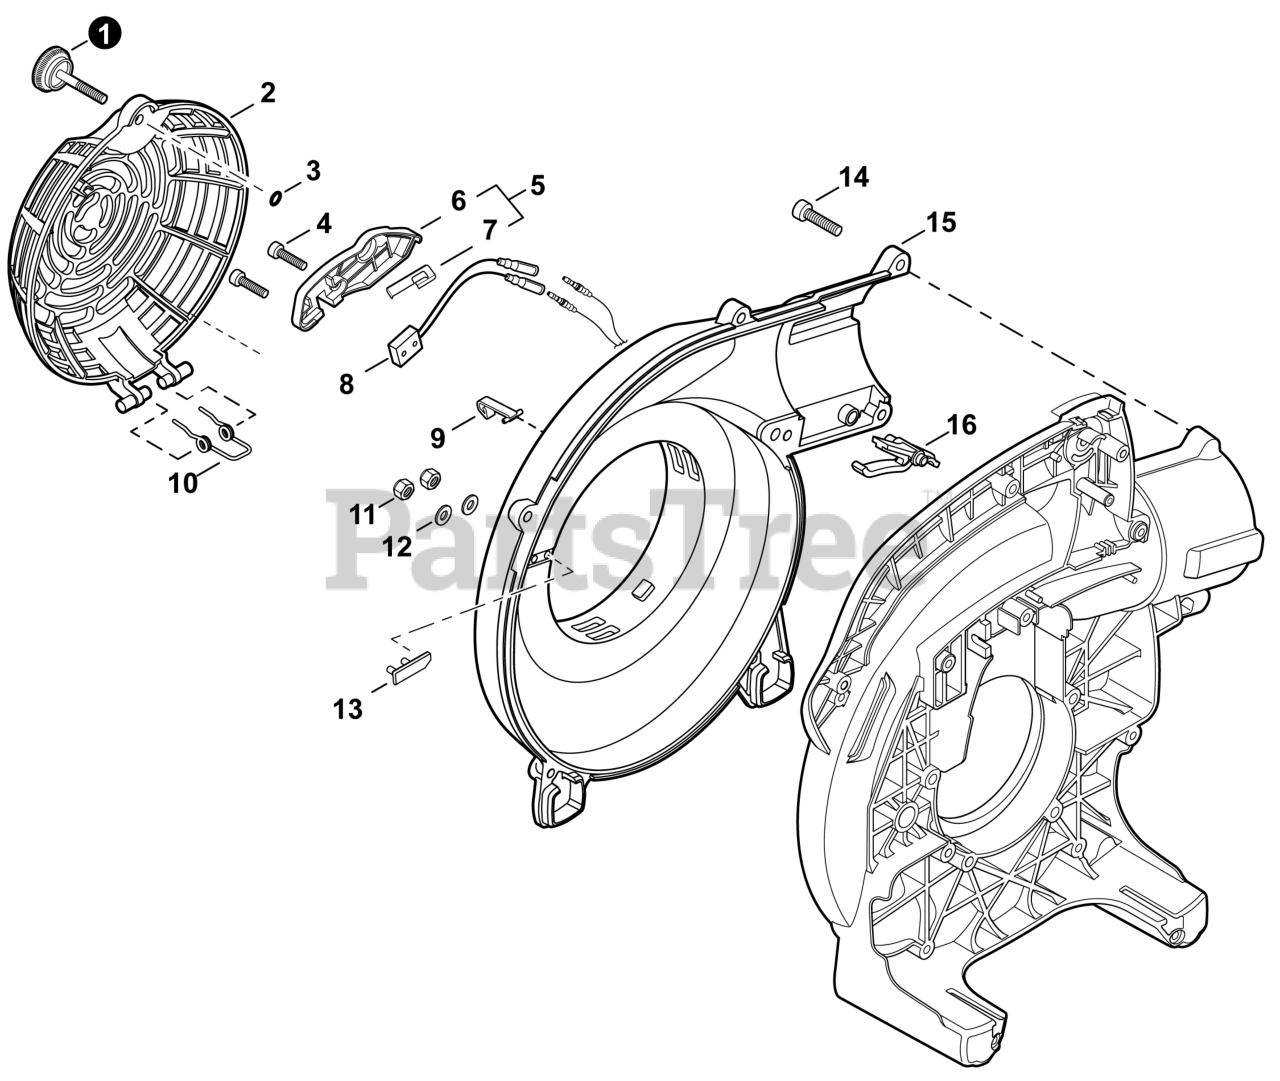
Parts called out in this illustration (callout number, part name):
1	THUMBSCREW
2	GUARD, FAN
3	O-RING 3
4	BOLT, TORX 4x16
5	KIT, SWITCH CASE
6	COVER, SWITCH
7	TERMINAL, LEAD
8	SWITCH, SAFETY
9	LEVER, ACTUATOR
10	SPRING, TORSION
11	NUT, LOCK M5
12	WASHER 5.5x12x0.8
14	BOLT, TORX 5x20
15	COVER, FAN
16	LOCK, TUBE
